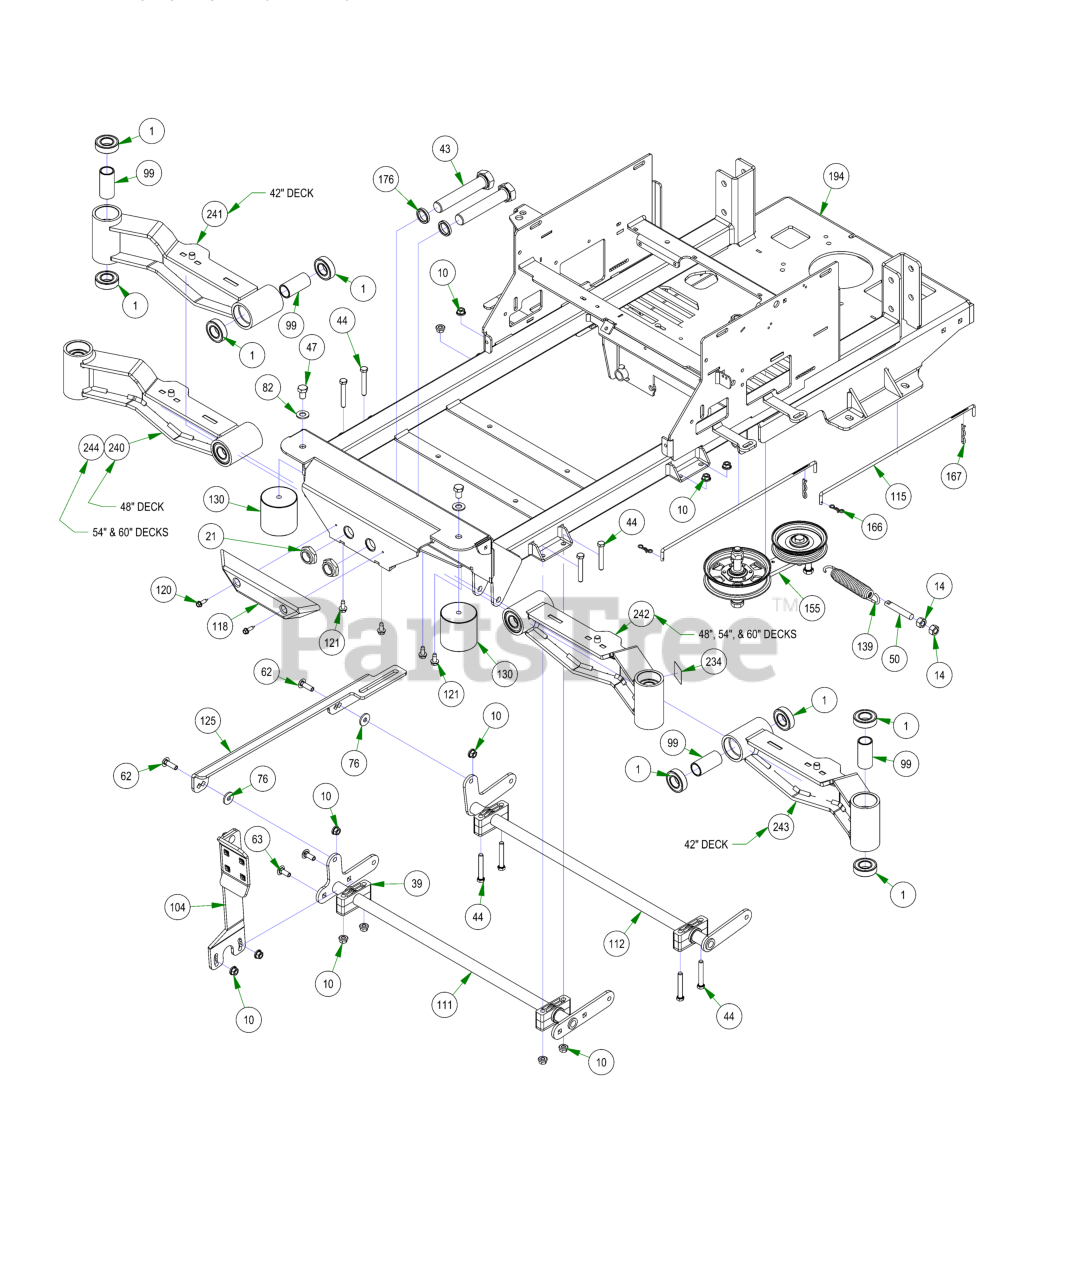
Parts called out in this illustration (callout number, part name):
1	1641 BEARING W/2 CONTACT RUBBER SEALS
10	3/8-16 NYLON INSERT FLANGE LOCKNUT (GR.F) ZINC
14	1/2-13 HEX NUT ZINC
21	1"-14 NYLON INSERT JAM LOCKNUT ZINC
39	Pillow Block Kit
43	1"-14 X 5-1/2 HEX CAP SCREW (GR.8) ZINC YELLOW
44	3/8-16 X 2-1/2 HEX CAP SCREW (GR.5) ZINC
47	1/2-13 X 3/4 HEX CAP SCREW (GR.5) ZINC
50	All Thread
62	3/8-16 X 1-1/4 CARRIAGE BOLT ZINC
63	3/8-16 X 1 CARRIAGE BOLT (GR.5) ZINC
76	.390 ID X 1.12 OD X .125 THK FLAT WASHER NYLON
82	1/2 SAE FLAT WASHER (1-1/16" OD) GR.8 ZINC YELLOW
99	2016 Front Bearing Spacer
104	Foot Pedal Assembly
111	Actuator Bar Front- 2017 MZ/ZT
112	Actuator Bar Rear- 2017 MZ/ZT
115	Neutral Rod
118	Bumper EZT
120	1/4 x 1 Hex Head Tek Screw
121	5/16-18 X 3/4 HEX WASHER SLOT (F) TCS ZINC
125	2017 MZ/ZT Actuator Linkage
130	Vibration Mount- Red Dot
139	Deck Idler Spring
155	Maverick Pump Idler
167	Neutral Rod Clip
176	Spacer, 1x1.375x.25
194	2023 Maverick Frame - Painted
234	Independetly Articulating Front Suspension Arms Patent Decal
240	2021 Maverick RH Short Front Suspension Arm Assy (48")
241	2022 42" Maverick I-Beam Front Arm - RH - Painted
242	2021 Maverick LH Front Suspension Arm Assy (48", 54" & 60")
243	2022 42" Maverick I-Beam Front Arm - LH - Painted
244	2021 Maverick RH Long Front Suspension Arm Assy (54" & 60")
